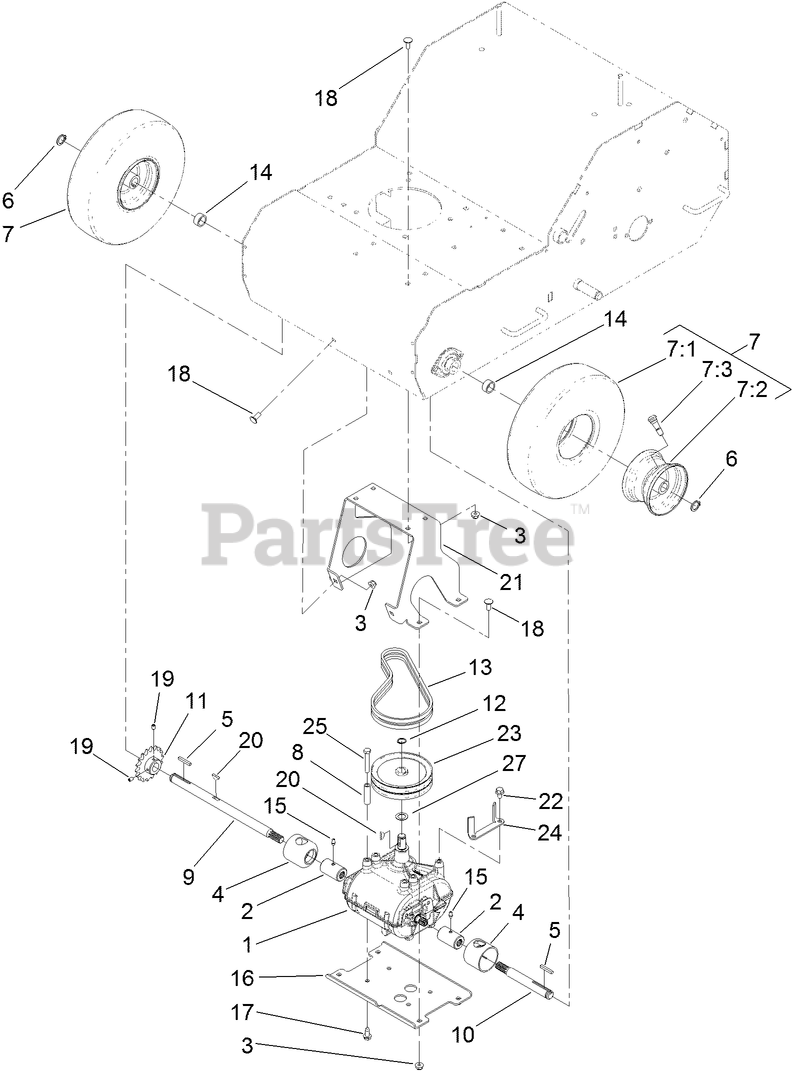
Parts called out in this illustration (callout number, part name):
1	TRANSMISSION
2	COUPLER
3	NUT-HF, NI
4	GUARD-COUPLER
5	KEY-SQUARE
6	RING-RETAINING
7	WHEEL ASM
7:2	WHEEL-RIM
7:3	VALVE
8	SPACER
9	SHAFT-TRANSMISSION
10	SHAFT-TRANSMISSION
11	SPROCKET, #40 18T
12	RING-SNAP, EXTERNAL
13	BELT-V, TRACTION
14	SPACER-WHEEL
15	FITTING-GREASE
16	MOUNT-TRANSMISSION, LOWER
17	SCREW-HWH, THREAD CUT
18	SCREW-CARR
19	SCREW-HSH
20	KEY-WOODRUFF
21	CHANNEL-MOUNT, TRANSMISSION
22	SCREW-HHF
23	SHEAVE
24	GUIDE-BELT
25	SCREW-HH
27	WASHER-FLAT
